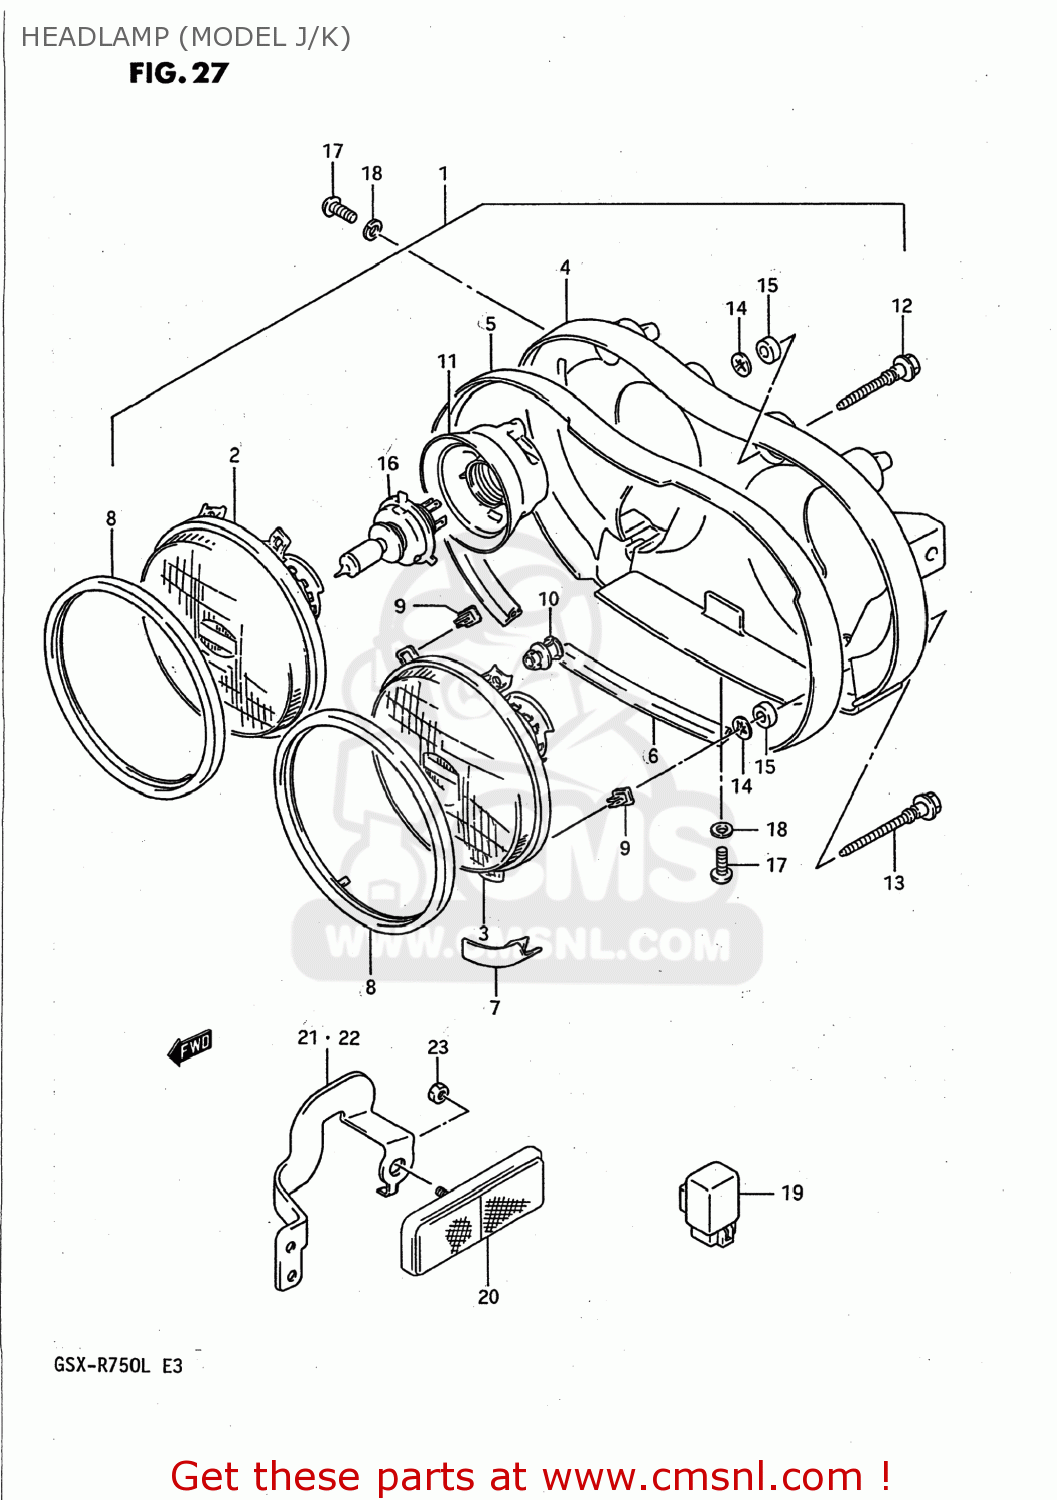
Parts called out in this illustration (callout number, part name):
1	HEADLAMP ASSEMBLY
2	LAMP UNIT,L
3	LAMP UNIT,R
4	HOUSING,HEAD LAMP
5	GASKET,HEADLAMP (NAS)
6	GASKET,HEADLAMP (NAS)
7	CUSHION
8	RING,RETAINING
9	NUT,HEADLAMP ADJUSTER
10	SCREW,SPHERICAL
11	COVER,SOCKET
12	SCREW,HEADLAMP ADJUST
13	SCREW,ADJUSTER
14	WASHER
15	BUSHING
16	BULB(12V60/55W,H4)
17	SCREW
18	WASHER,LOCK
19	RELAY ASSY,HEADLAMP
20	REFLEX REFLECTOR,FR SIDE
21	BRACKET,REFLECTOR
22	BRACKET
23	NUT
